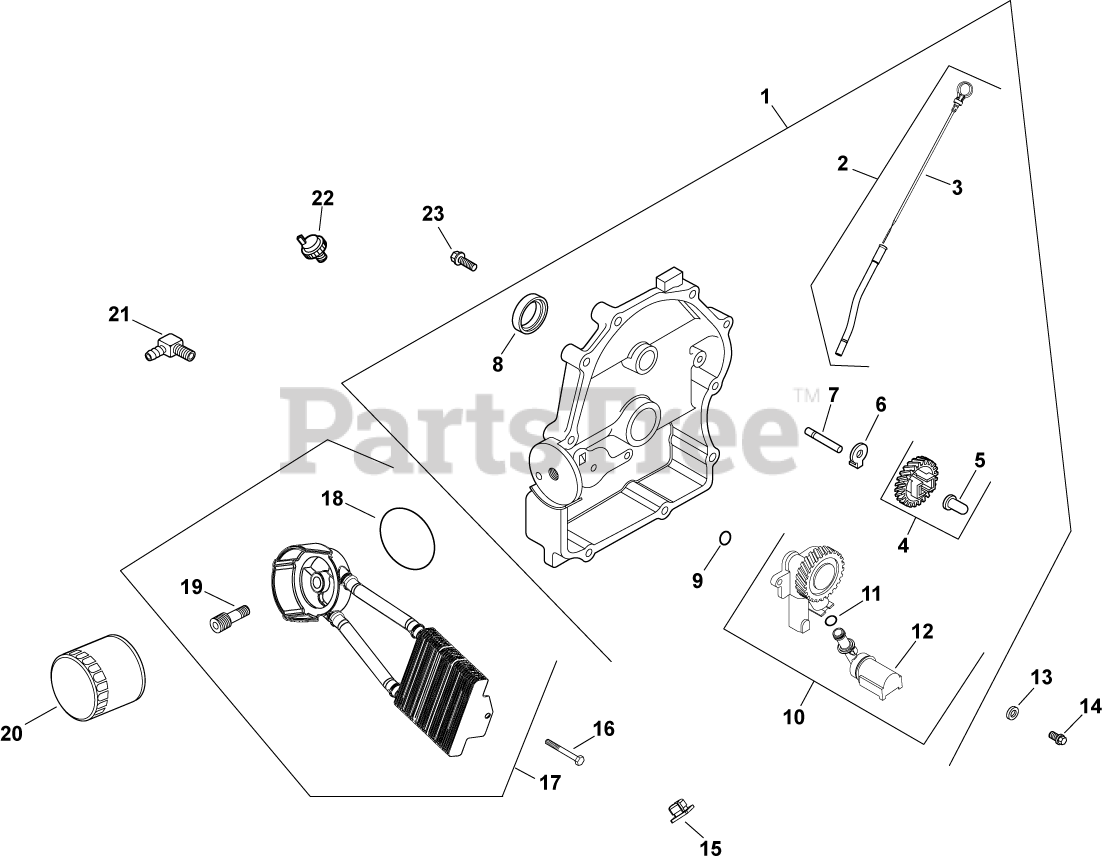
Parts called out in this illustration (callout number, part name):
1	PLATE, CLOSURE & BEARING USE 24 009 227-S
2	KIT, DIPSTICK/DIPSTICK TUBES
4	KIT, GOVERNOR GEAR W/PIN
5	PIN, GOVERNOR REGULATING
6	TAB, LOCKING
7	SHAFT, GOVERNOR GEAR
8	SEAL, OIL (KM)-USE 25 032 06-S
10	PUMP ASSEMBLY, OIL-USE 24 393 53-S
11	O-RING, OIL PICK-UP
12	PICK-UP, OIL
13	WASHER, FLAT 6 MM
14	SCREW,FLG THD FRM M6X1.0X25-(#25086395S)
15	NUT, PLASTIC (KM)-USE 25 100 37-S
16	SCREW, TAPPING
17	KIT, OIL COOLER
18	O-RING, OIL COOLER
19	NIPPLE, OIL FILTER
20	OIL FILTER
21	CONNECTOR, 90 DEG. HOSE
22	SENSOR, OIL PSI
23	SCREW, FLG M8X1.25X45
2409903-S	SENSOR, OIL PSI
